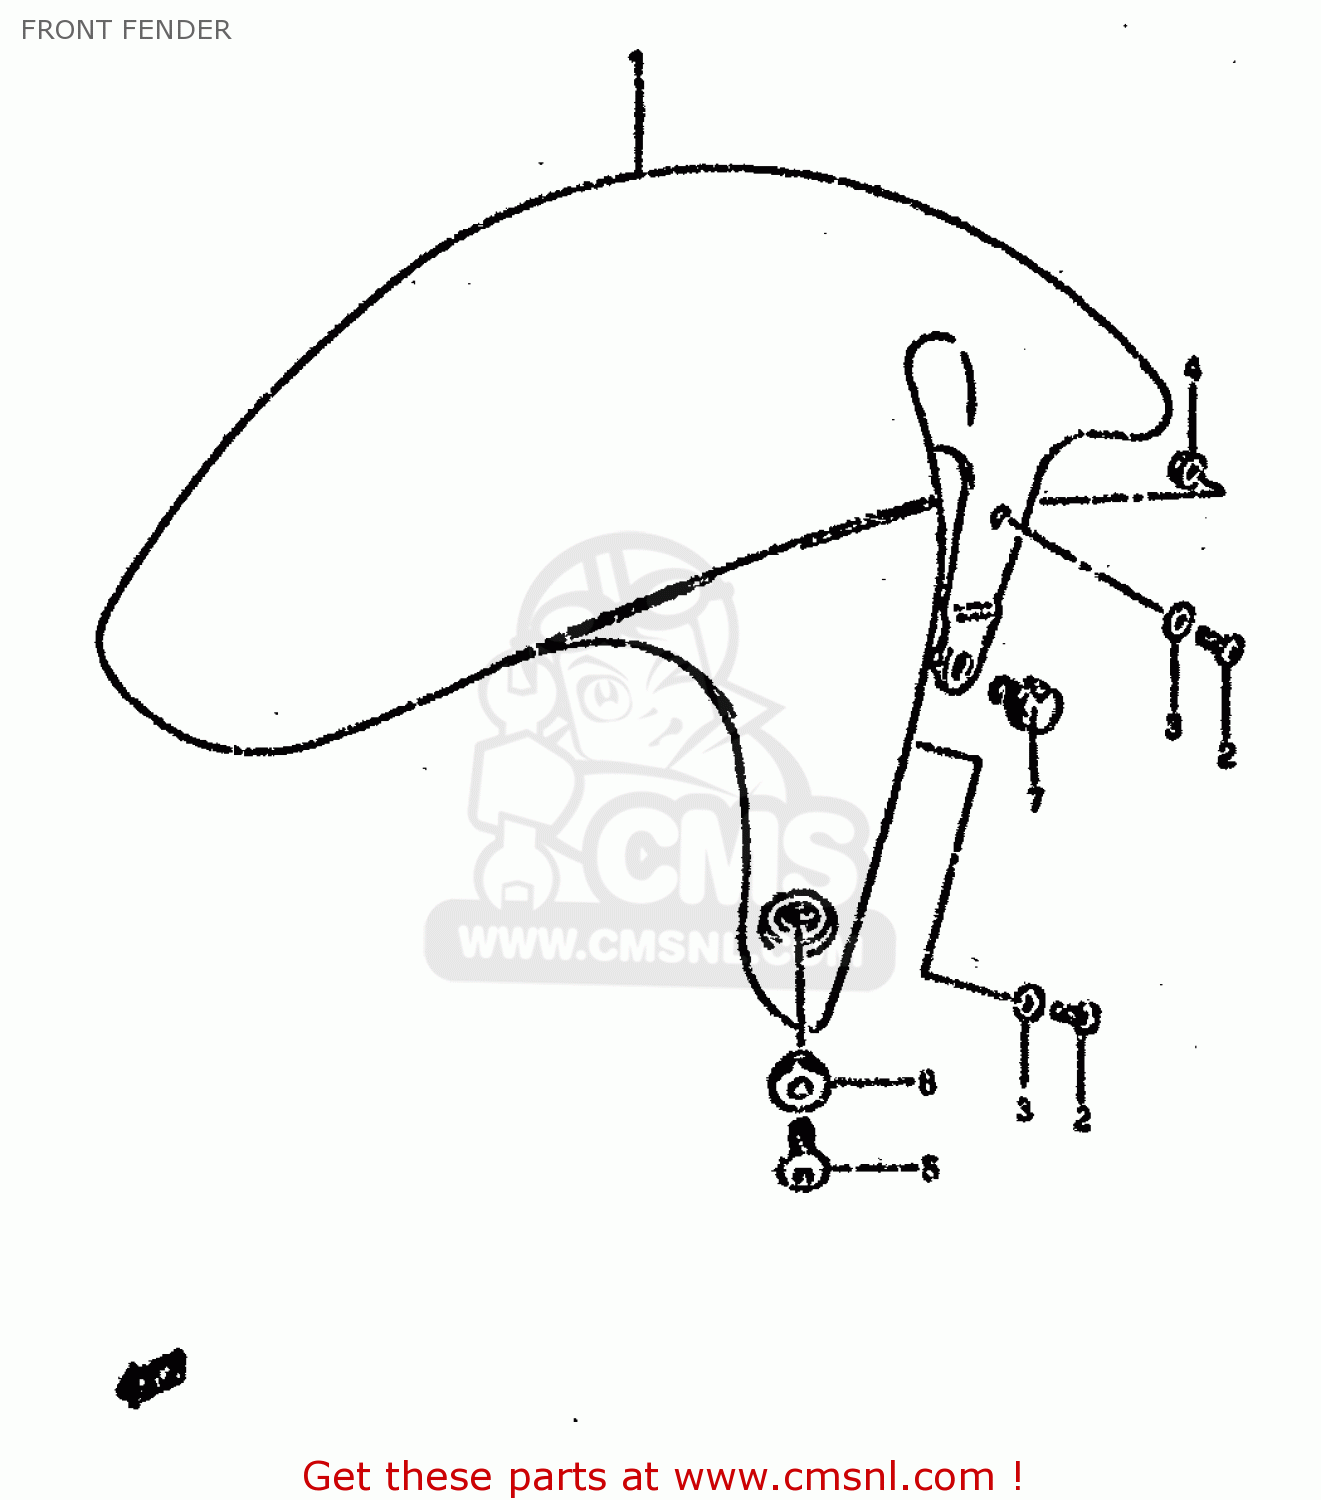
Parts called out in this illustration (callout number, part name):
1	FENDER,FR
2	SCREW
3	WASHER
4	NUT
5	SCREW(6X16)
6	WASHER(6.3X16X1.5)
7	BOLT
